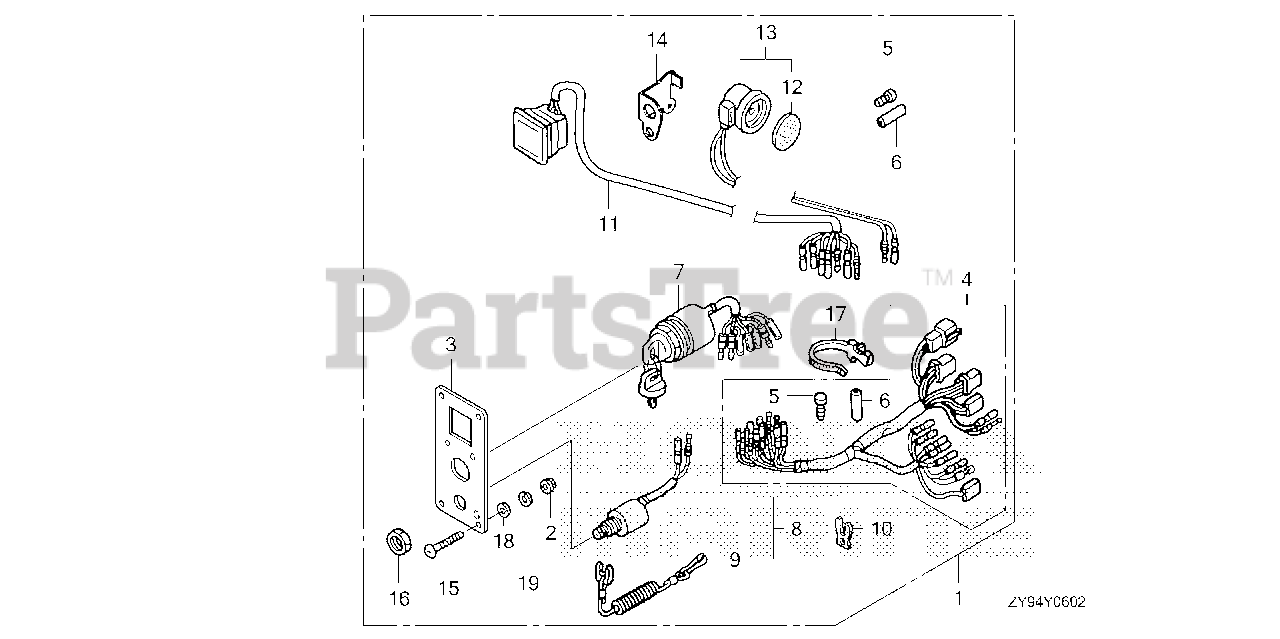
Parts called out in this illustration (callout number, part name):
1	PANEL KIT, SWITCH (4-LED)
2	NUT, FLANGE (5MM)
3	PANEL, CONTROL
4	HARNESS ASSY., SWITCH PANEL
5	PLUG, CONNECTOR (INNER)
6	PLUG, CONNECTOR (OUTER)
7	SWITCH ASSY., COMBINATION
8	SWITCH ASSY., EMERGENCY STOP
9	WIRE, EMERGENCY
10	CLIP, EMERGENCY LOCK
11	LAMP ASSY., INDICATION (4-LED)
12	PLATE, TURN SIGNAL BUZZER
13	BUZZER, WARNING
14	BRACKET, BUZZER
15	SCREW, PAN (5X40)
16	NUT, HEX. (16MM)
17	BAND, WIRE HARNESS (150MM) (NATURAL)
18	WASHER, PLAIN (5MM)
19	WASHER, SPRING (5MM)
